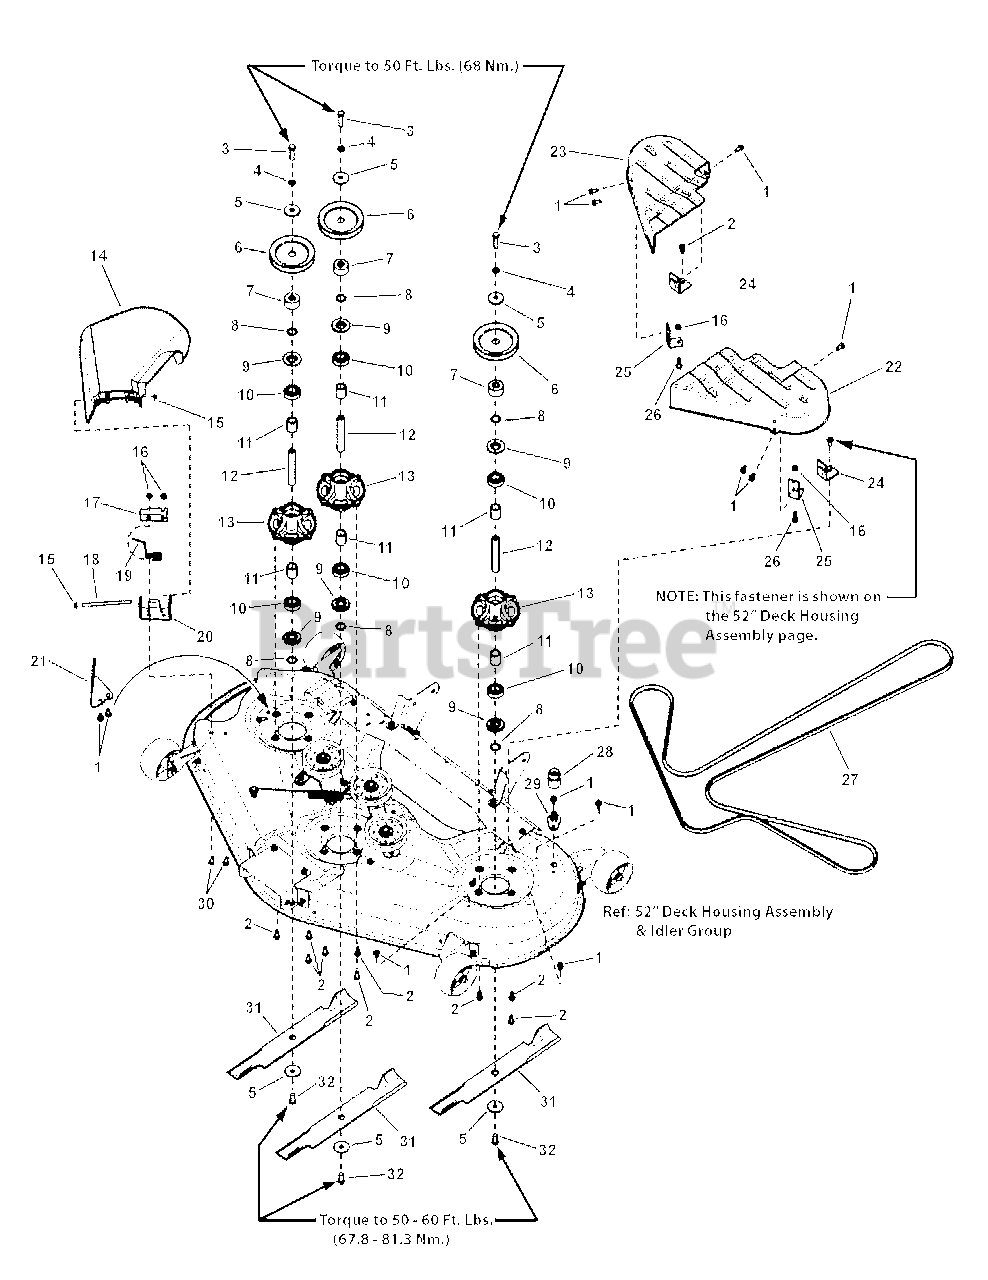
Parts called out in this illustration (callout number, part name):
1	SCREW, 5/16-18 x 3/4" Hex Washer Head Self-Tap, Black
2	SCREW, 5/16-18 x 1" Hex Washer Head Self-Tap, Black
3	SCREW, 7/16-14 x 1-3/4" Hex Head Cap, GR 5, Black
4	LOCKWASHER, .438, Spring, Black
5	WASHER, .475 ID x 1.75 OD x .156 Thick Spring, Black
6	PULLEY, 5.5 OD 11 Ga. Split 52" Mower
7	SPACER, Pulley, Powdered Metal
8	RING, Self Locking
9	SHIELD, Arbor, 2.050 OD
10	BALL BEARING, 20 MM
11	SPACER, Bearing Powdered Metal
12	SHAFT, Spindle 20MM Dia. 134.60 MM Long
13	HOUSING, Spindle, Cast Aluminum (Machined) w/Grease Fitting
14	DEFLECTOR, Discharge, Plastic 46/52 Decks
15	PUSH NUT, 5/16"
16	NUT, 5/16-18 Hex Flange Lock, Small - Black
17	PLATE, Deflector, Closeoff
18	ROD, Hinge, .313 Dia. x 5.6 Long, Zinc Plated
19	SPRING, Torsion, Deflector, 2.16 Long
20	HINGE, Deflector, 52"
21	BAFFLE, Pinchoff
22	COVER, Spindle, 46/52 Deck, LH 285Z
23	COVER, Spindle, 46/52 Deck, RH 285Z
24	BRACKET, Rear Deck Cover Support 285Z
25	BRACKET, 46"/52" Cover Mounting
26	SCREW, 5/16-18 x 1-1/4" Hex Washer Face Self-Tap
27	BELT, RZT, 52" Deck, HA Section, 158" Effective Length
28	CONNECTOR, Washout Port 46/52" Black Poly
29	ADAPTER, Washout Port 46/52" Mowers
30	BOLT, 5/16-18 x 7/8" Round Head Short Square Neck, GR 5, Black
31	BLADE, Mower, 18.50 Long, 52" Deck
32	SCREW, 7/16-14 x 1" Hex Head Cap, GR 5, Black
